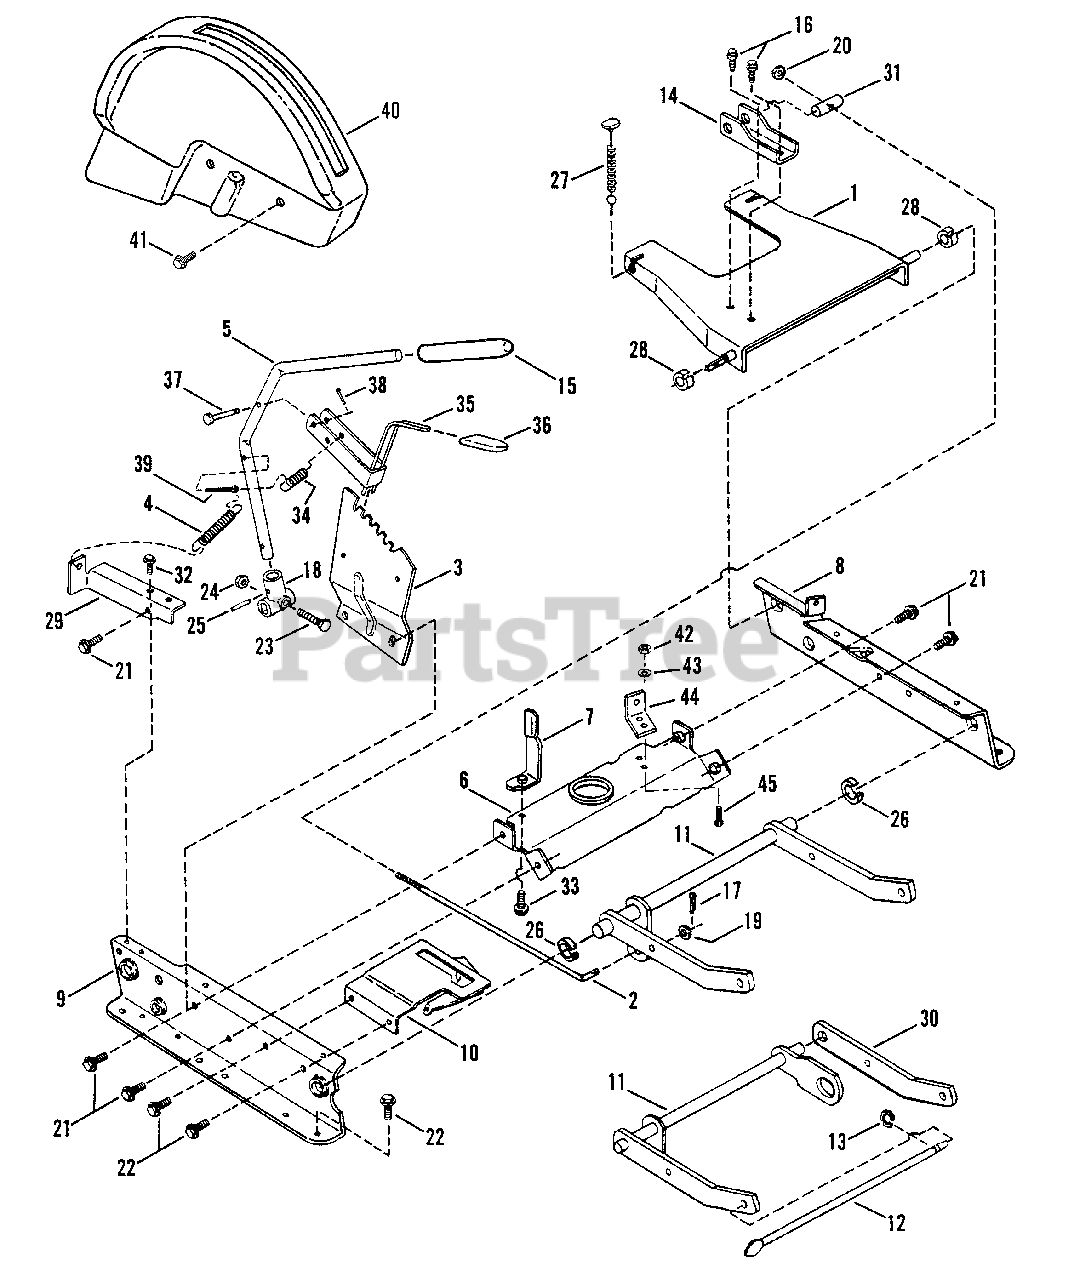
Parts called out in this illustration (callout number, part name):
1	ARM, Rear Lift
2	ROD, Leveling
3	QUADRANT, Lift Lever
4	SPRING, Extension
5	LEVER, Lift
6	BRACE, Top
7	GUIDE, Belt
8	RAIL, Left Hand
9	RAIL, Right Hand
10	ASSEMBLY, Clutch Plate
11	ARM, Front Lift, Non-Adjustable
12	ROD, Support (Front Lift Arm to Front End)
13	RING, 7/16 Retaining
14	ARM, Leveling
15	GRIP, Height Adjustment Lever
16	SCREW, 5/16-18 x 5/8" Self-Tapping (Torx)
17	PIN, 1/8 x 3/4" Cotter
18	HUB, Deck Lift
19	WASHER, 3/8" Flat
20	NUT, 3/8-24 Hex Nyloc
21	SCREW, 3/8-16 x 5/8" Self-Tapping
22	SCREW, 5/16-18 x 1/2" Self-Tapping
23	BOLT, 5/16-24 x 1-5/8" Tapered Axle
24	NUT, 5/16-24 Hex Flange Lock
25	PIN, 3/16 x 1" Roll
26	RING, Red
27	CABLE, Rear Deck 5"
28	RING, White
29	BRACKET, Deck Lift
30	ARM, Front Lift-Left
31	PIVOT, Leveling
32	SCREW, 1/4-20 x 3/8" Self-Tapping
33	SCREW, 5/16-18 x 5/8" Self-Tapping
34	SPRING, Latch
35	LATCH
36	GRIP, Lift Latch
37	PIN, Clevis
38	PIN, 1/16 x 3/4" Cotter
39	PIN, 3/16 x 1 1/2" Cotter
40	COVER, Height Adjustment
41	SCREW, 1/4-20 x 5/8" Self-Tapping
42	NUT, 5/16-24 Hex
43	WASHER, 5/16 Internal Tooth Lock
44	ANCHOR
45	SCREW, 5/16-24 x 3/4" Hex Head Cap
